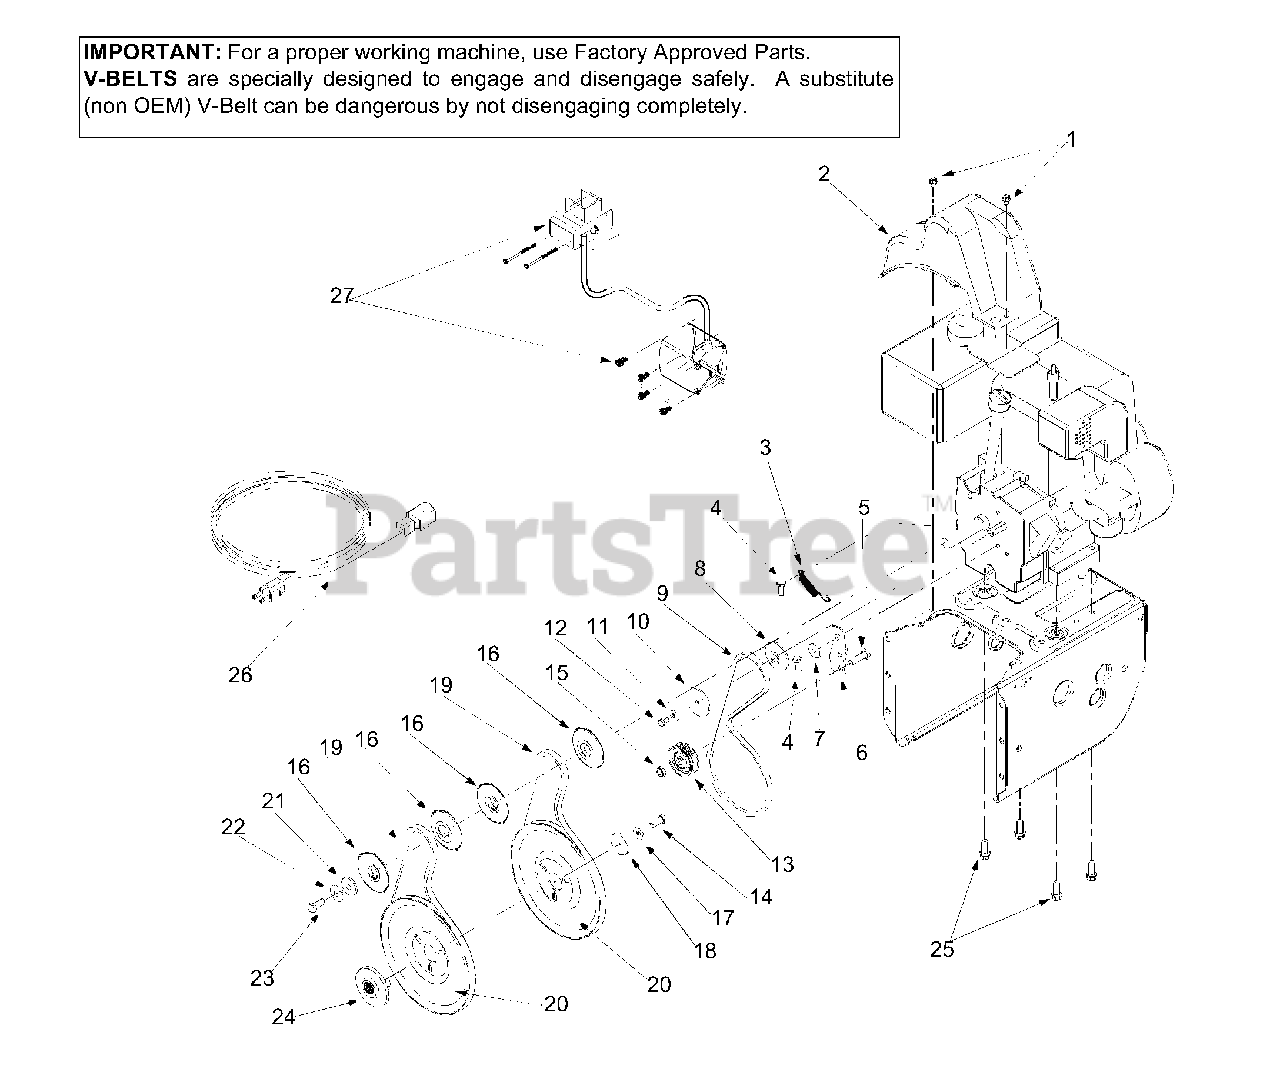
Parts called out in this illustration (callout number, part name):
1	Hex Washer Screw 1/4-20 x .625
2	Belt Cover
3	Extension Spring
4	Hex Screw 5/16-24 x .75
5	Hex Cap Screw 3/8-16 x 1.25
8	Pulley Half
9	V-Belt
10	Pulley Half
11	Bell Washer
12	Hex Cap Screw 1/4-28 x .50
13	Flat Idler
14	Lock Hex Cap Screw 5/16-24
15	Lock Jam Nut 3/8-16
16	Pulley Half
17	Bell Washer
18	Flat Washer
19	Belt
20	Auger Pulley
21	Flat Washer 3/8 x 1.25 OD
22	Bell Washer
23	Hex Cap Screw 3/8-24
24	Adapter Pulley
25	Hex Screw 3/8-16 x 1.0
26	Extension Cord
27	Electric Start
